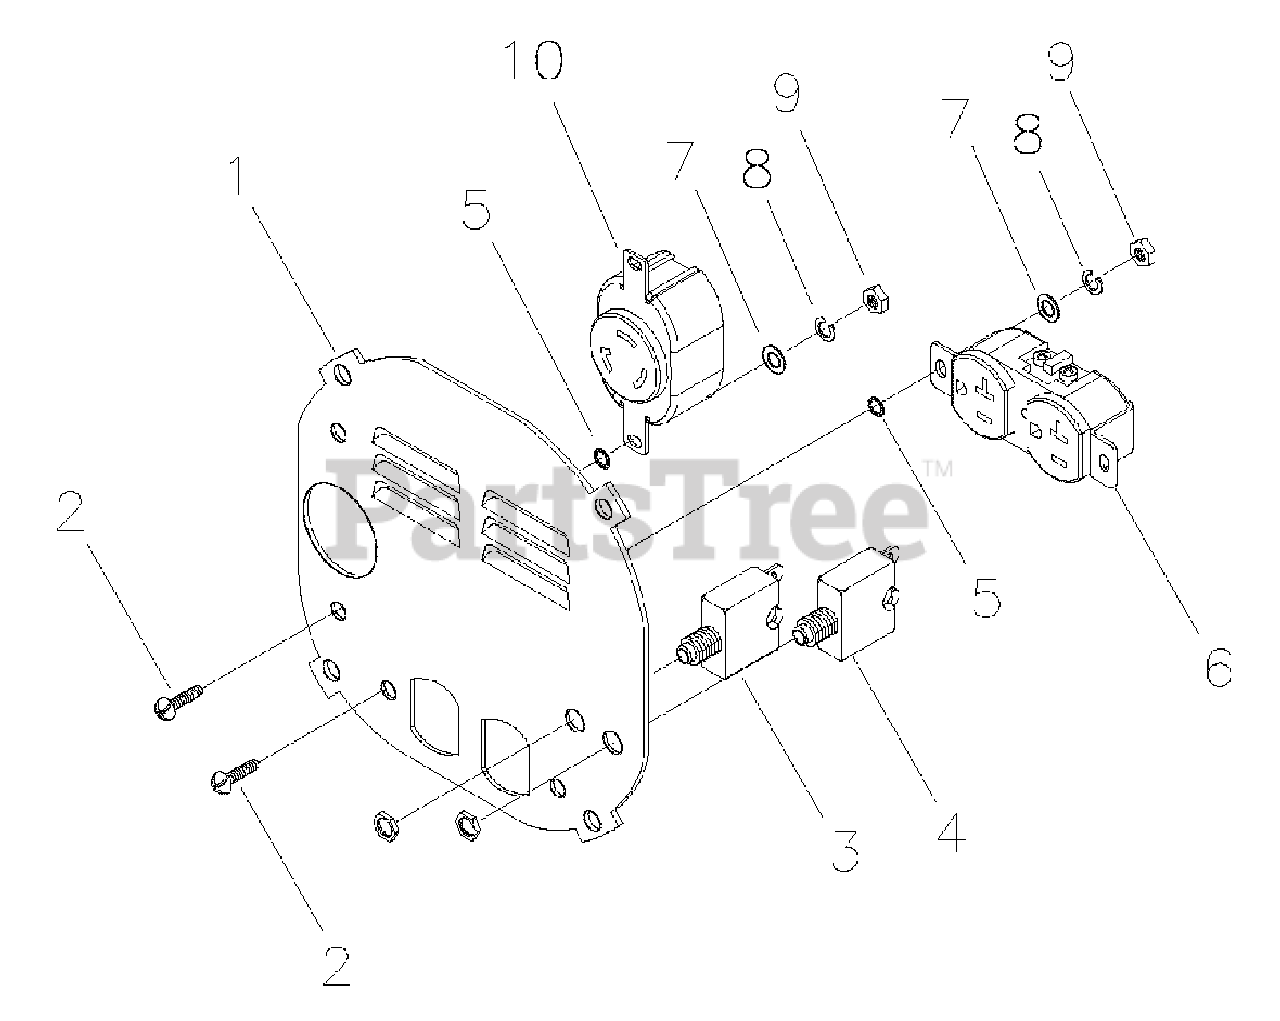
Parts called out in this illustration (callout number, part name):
1	COVER, Control Panel
3	BREAKER, Circuit
4	BREAKER, Circuit
6	OULET, 120V, 20A Duplex
8	WASHER, Lock
10	OUTLET, Locking, 120V AC, 30A
